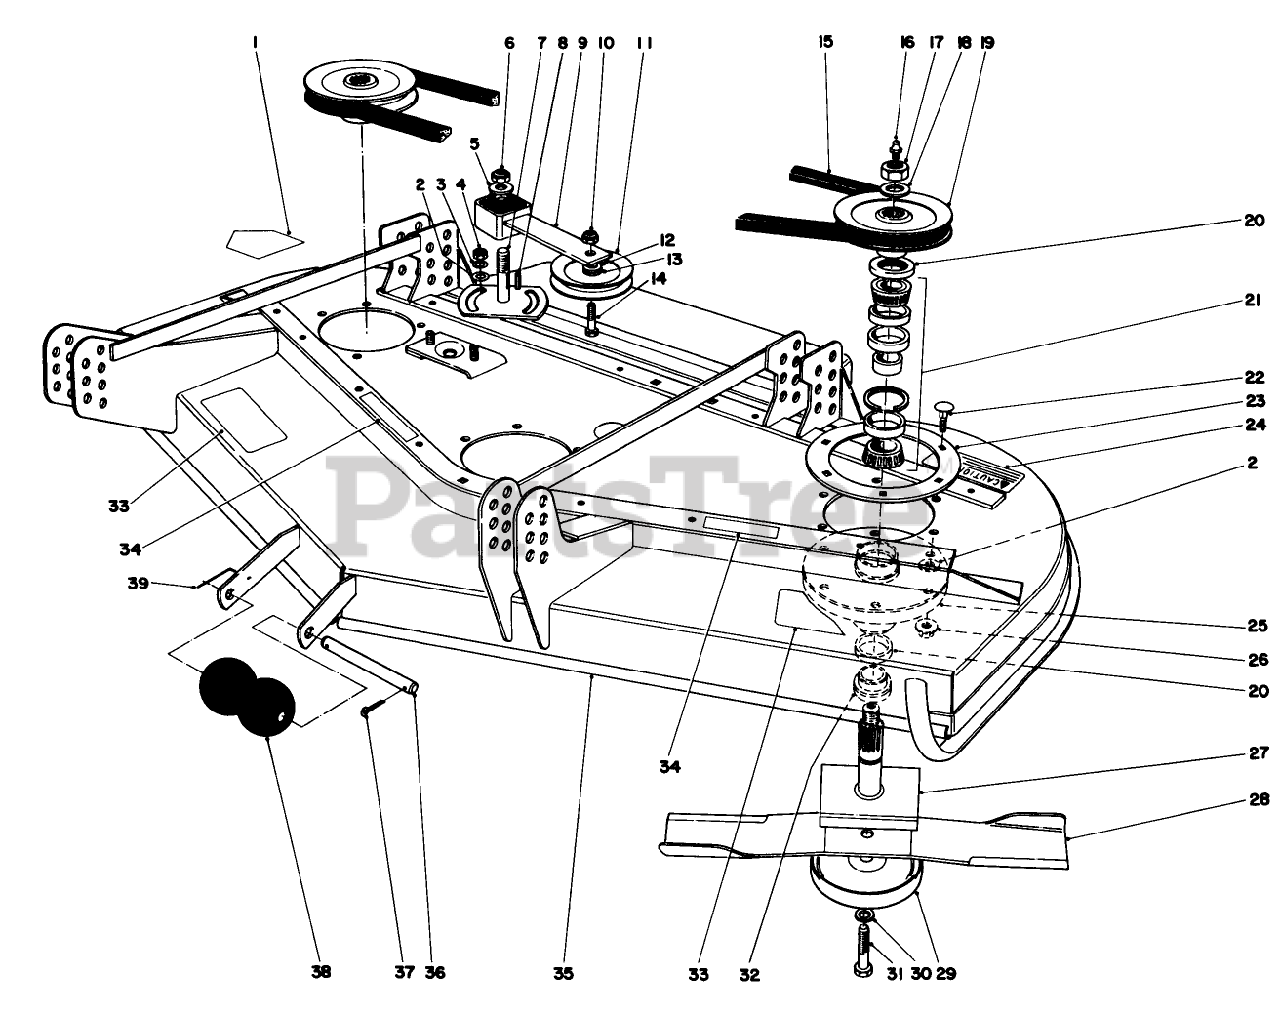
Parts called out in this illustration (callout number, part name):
1	DECAL-DANGER
2	WASHER-FLAT
3	WASHER-LOCK/SP
4	NUT-JAM
5	WASHER-FLAT
6	NUT-LOCK, NI
7	PLATE-IDLER
8	KEY-SQUARE
9	IDLER ARM ASM
10	NUT-HEX
11	PULLEY-IDLER
12	WASHER-FLAT
13	BUSHING-PULLEY
14	SCREW-HH
15	V-BELT
16	FITTING-GREASE
17	NUT-HEX
18	WASHER
19	PULLEY AND HUB ASM
20	SEAL-OIL
21	BEARING ASM
22	SCREW-CARR
23	SUPPORT-DECK, RING
24	DECAL-TORQUE
25	HOUSING-SPINDLE
26	NUT-HF
27	SHAFT
28	Blade
29	Cup-Scalp
30	WASHER-LOCK
31	SCREW-BLADE
32	SPACER
33	DECAL-DANGER, THROWN OBJECT
34	DECAL-DANGER
35	CUTTER DECK WA RO
36	SHAFT-ROLLER
37	PIN-COTTER
38	ROLLER
39	PIN-SPECIAL
